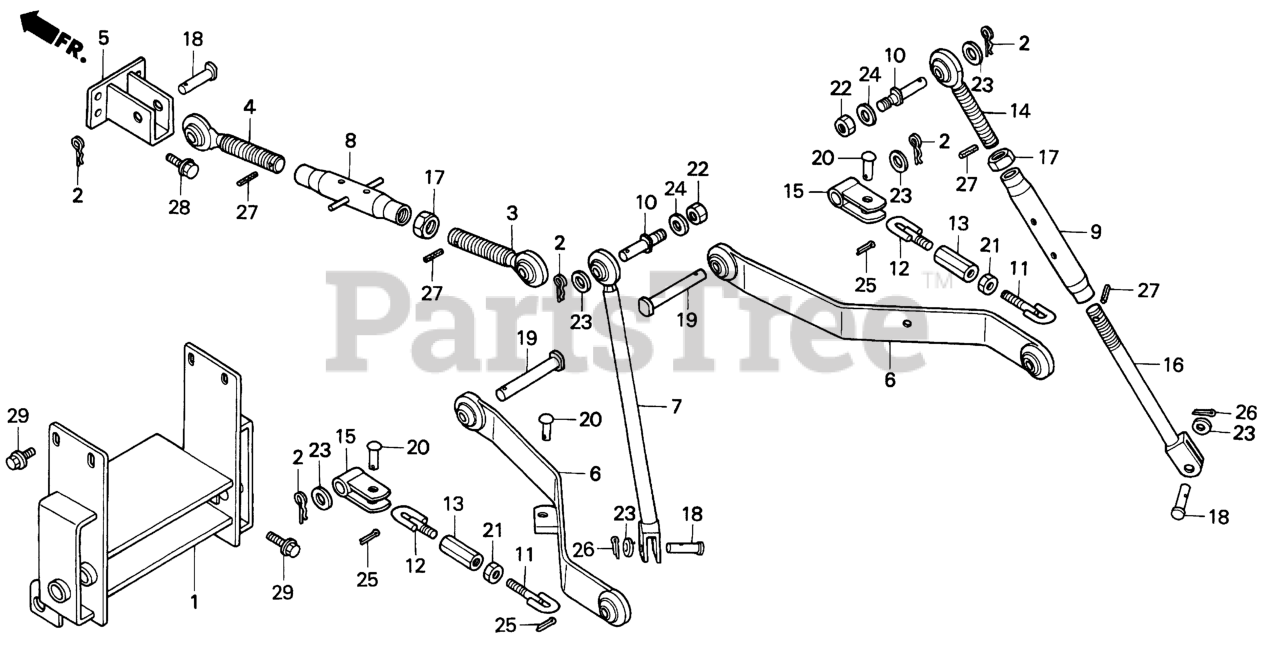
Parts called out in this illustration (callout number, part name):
1	BOX, HITCH (NOT AVAILABLE)
2	PIN, LOCK
3	HOLDER, R. LINK (UPPER)
4	HOLDER, L. LINK (UPPER)
5	BRACKET, LINK (UPPER)
6	LINK (LOWER)
7	ROD, L. LIFT
8	BUCKLE, LINK TURN (UPPER)
9	BUCKLE, LIFT ROD TURN
10	PIN, LIFT ROD
11	BOLT A, TURN BUCKLE
12	BOLT B, TURN BUCKLE
13	BUCKLE, TURN
14	ROD, R. LIFT (UPPER)
15	BRACKET, TURN BUCKLE
16	ROD, R. LIFT (LOWER)
17	NUT, HEX. (20MM)
18	PIN, LINK (UPPER)
19	PIN, LINK (LOWER)
20	PIN, TURN BUCKLE
21	NUT, HEX. (12MM) Use up to Frame SN 5002482.
22	NUT, HEX. (16MM)
23	WASHER, PLAIN (16MM)
24	WASHER, SPRING (16MM)
25	PIN, COTTER (3.0X18)
26	PIN, COTTER (4X25)
27	PIN, SPRING (4X20)
28	BOLT, FLANGE (8X20)
29	BOLT, FLANGE (10X25)
